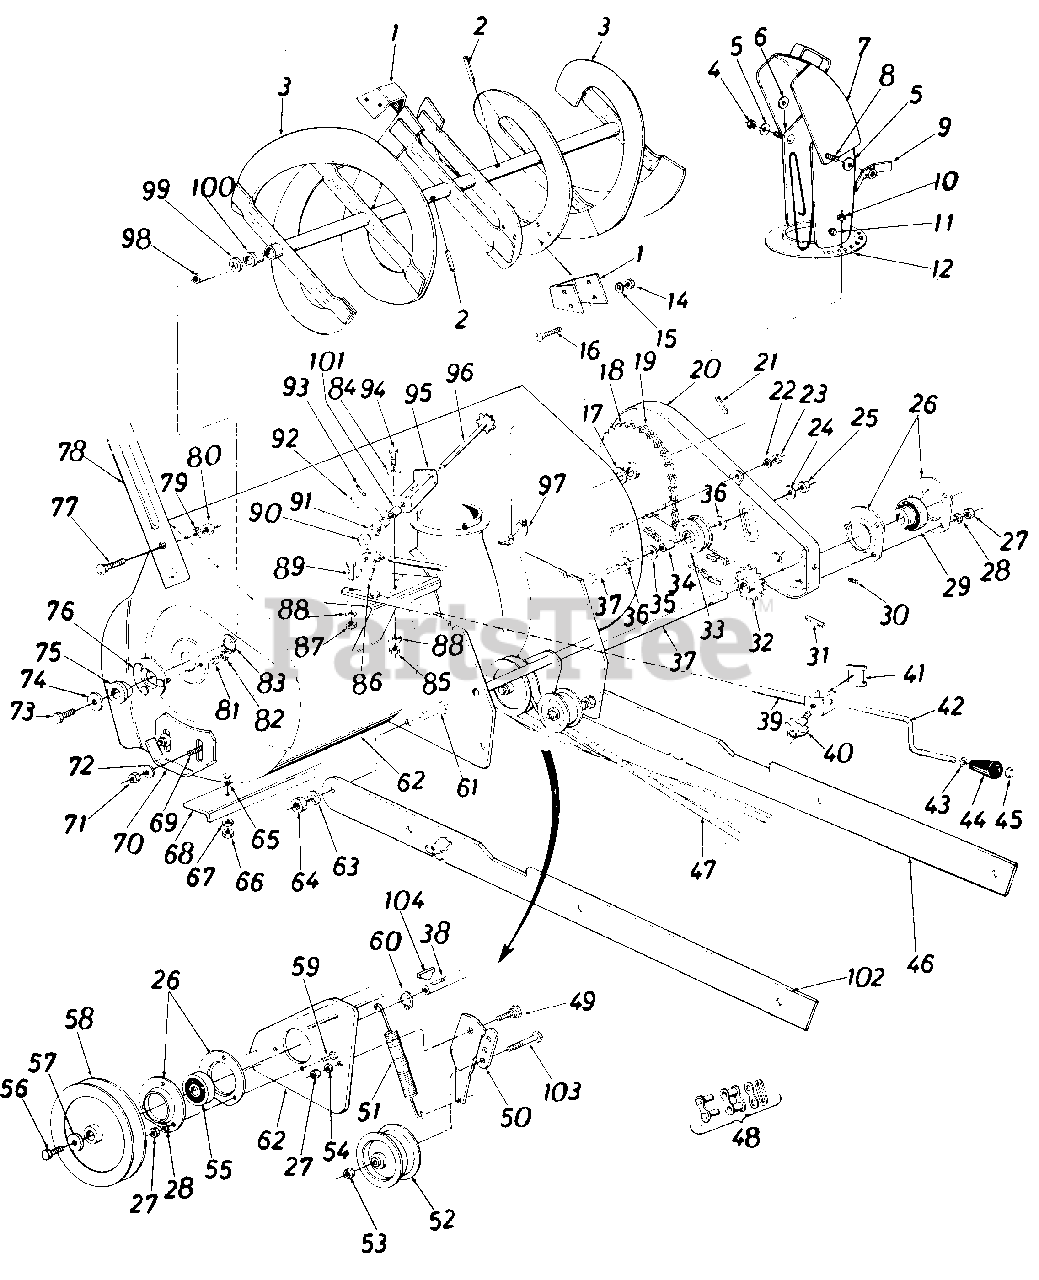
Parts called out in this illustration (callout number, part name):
1	Spiral Plate
2	Spring Pin Spir. 5/16 x 1.75" Lg.
3	Spiral Ass'y.
4	Hex Cent. L-Nut 5/16-18 Thd.
5	Bell. Wash.
6	Fl-Wash.
7	Top Chute Ass'y.
8	Car. Bolt 5/16-18 x .62" Lg.
9	Chute Wing Ass'y.
10	Hex Cent. LNut 1/4-20 Thd.
11	Push Cap.188" Dia. Rod
12	Chute Ass'y.
14	Hex Nut 5/16-18 Thd.*
15	L-Wash. 5/16" Scr.*
16	Car. Bolt 5/16-18x.62" Lg.*
17	Fl-Wash.
18	Sprocket Hub Ass'y.-40 Teeth
19	#420Chainx 1/2" Pitch-77 Links
20	Chain Guard Ass'y.
21	Spring Pin Spir. - 5/16
22	L-Wash. 5/16" Scr.*
23	Hex Nut 5/16-18 Thd.*
24	Bell. Wash.
25	Hex Ins. L-Nut 3/8-16 Thd.
26	Bearing Housing
27	Hex Nut 5/16-18 Thd.*
28	L-Wash. 5/16" Scr.*
29	Self Aligning Brg. w/Set Scr.
31	Spring Pin Spir.-5/16x 1.75
32	14 Teeth Sprocket Ass'y.
33	1.875" Dia. Flat Idler
34	Idler Spacer
35	F l-Wash .
36	Fl-Wash.
37	Hex Scr. 3/8-16x 2.00" Lg.*
38	Drive Shaft
39	Crank Support Tubing Ass'y.
40	Hand Knob 5/16-18 Thd.
41	Chute Crank Brkt.
42	Chute Crank
43	Fl-Wash.
44	Knob-Black 3/8" Dia. Hole
45	Push Nut 3/8" Rod
46	Linkage Arm Ass'y.
47	"V"-Belt 1/2"x85" Lg. [ (Kevlar)
48	Master Link for #420 Chain
49	Shoulder Scr.
50	Idler Brkt. Ass'y.
51	Extension Spring
52	Fl. Idlerwith Flange
53	Hex Ins.Jam Nut 3/8-1 Thd.
54	L-Wash. 5/16" Scr.*
55	Self Aligning Brg.
56	Hex Scr. 5/16-18x.62" Lg.
57	F l-Wash.
58	5.50 O.D. x 5/8 Pulley
59	Hex Sems Scr. 5/16-18 x .75"
60	Snap Ring for .75 Dia. Shaft
61	Hex Scr. 1/2-13 x 1.25" Lg.*
62	Spiral Housing Ass'y.
63	L-Wash. 1/2" Scr.*
64	Hex Nut 1/2-13 Thd.*
65	Car. Bolt 5/16-18 x .62" Lg.*
66	Hex Nut 5/16-18 Thd.*
67	L-Wash. 5/16" Scr.*
69	Car. Bolt 3/8-16x.75" Lg.*
72	Bell. Wash.
73	Hex Scr. 5/16-18x.62" Lg.
74	Fl-Wash.
75	Flange Brg. with Flats
76	Brg. Housing Ass'y.
77	Car. Bolt 5/16-18 x .62" Lg.
78	Guide Blade
79	L-Wash. 5/16" Scr.*
80	I-lex Nut 5/16-18 Thd.*
81	L-Wash. 5/16" Scr.*
82	Hex Nut 5/16-18 Thd.*
83	Snap Ring for 1.50" Dia. Shaft
84	Bell. Wash.
85	Hex Nut 5/16-18 Thd.*
86	Cotter Pin 3/32 x 1.00" Lg.*
87	Hex Nut 5/16-18 Thd.*
88	L-Wash. 5/16" Scr.*
89	Hex Scr. 5/16-18 x 1.50" Lg.
90	Joint Block
91	Joint Brkt. Ass'y.
92	Spring Pin Roll 3/16" x .81" Lg.*
93	Spring Pin Roll 1/8x.75" Lg.*
94	Hex Scr. 5/16-18x.75" Lg.*
95	Chute Brkt.
96	Sprocket Shaft Ass'y.
97	Chute Flange Keeper Ass'y.
98	Spiral Axle
99	Fl-Wash .
100	Plastic Bushing
101	Spacer .380 I.D. x.630 O.D. x .565
102	Linkage Arm Ass'y. - R.H.
103	Hex Bolt 3/8-16 x 1.75" Lg.*
104	#61 Hi-Pro Key
